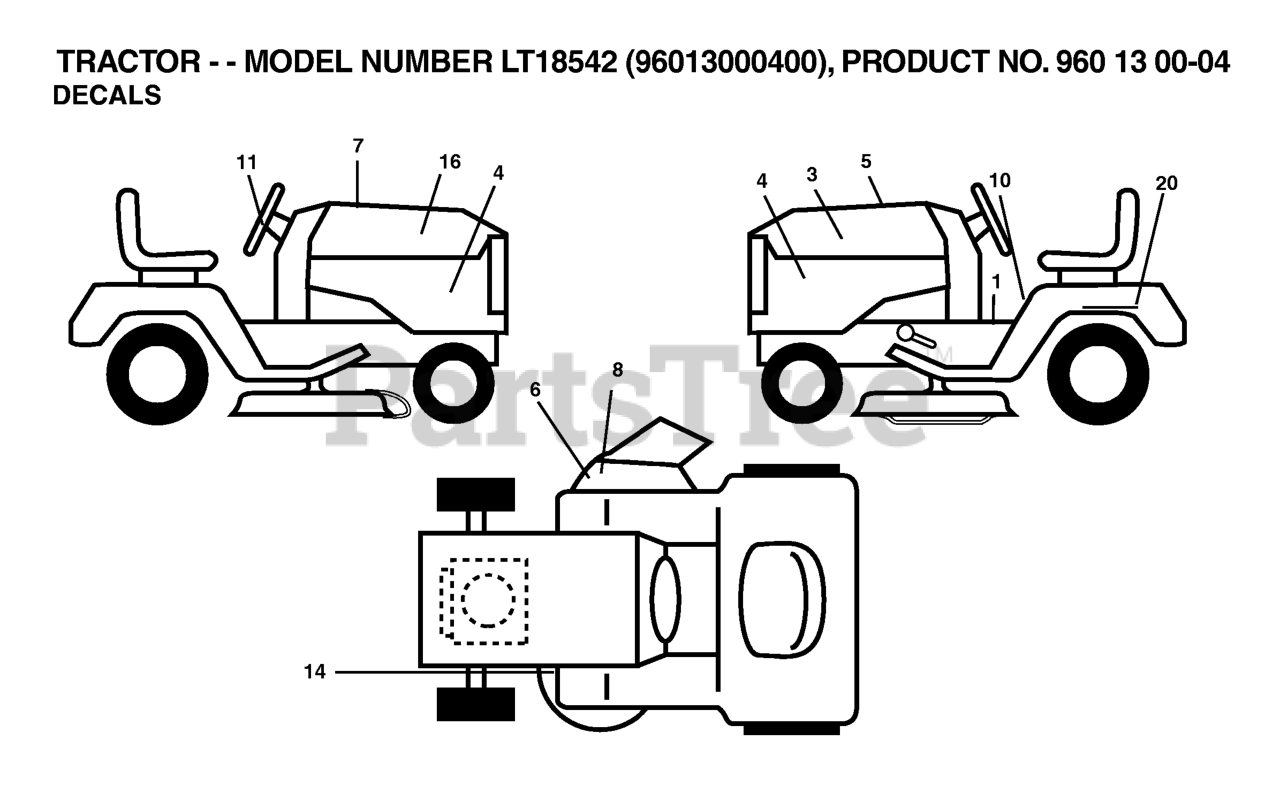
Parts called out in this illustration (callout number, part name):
4	DECAL.PNL.SD.LT18542.CDA.ONLY
5	DECAL HOOD CUST. RESP.
6	DECAL.WARN.KEEP.HAND.AWAY
7	DECAL RPL LT18542
8	DECAL DECK "B" 42"
10	DECAL FENDER DANGER
11	DECAL.STEERING.HUSQ.BLUE
14	DECAL V BELT SCHEMATIC
20	DECAL BTRY SYMBOLS
